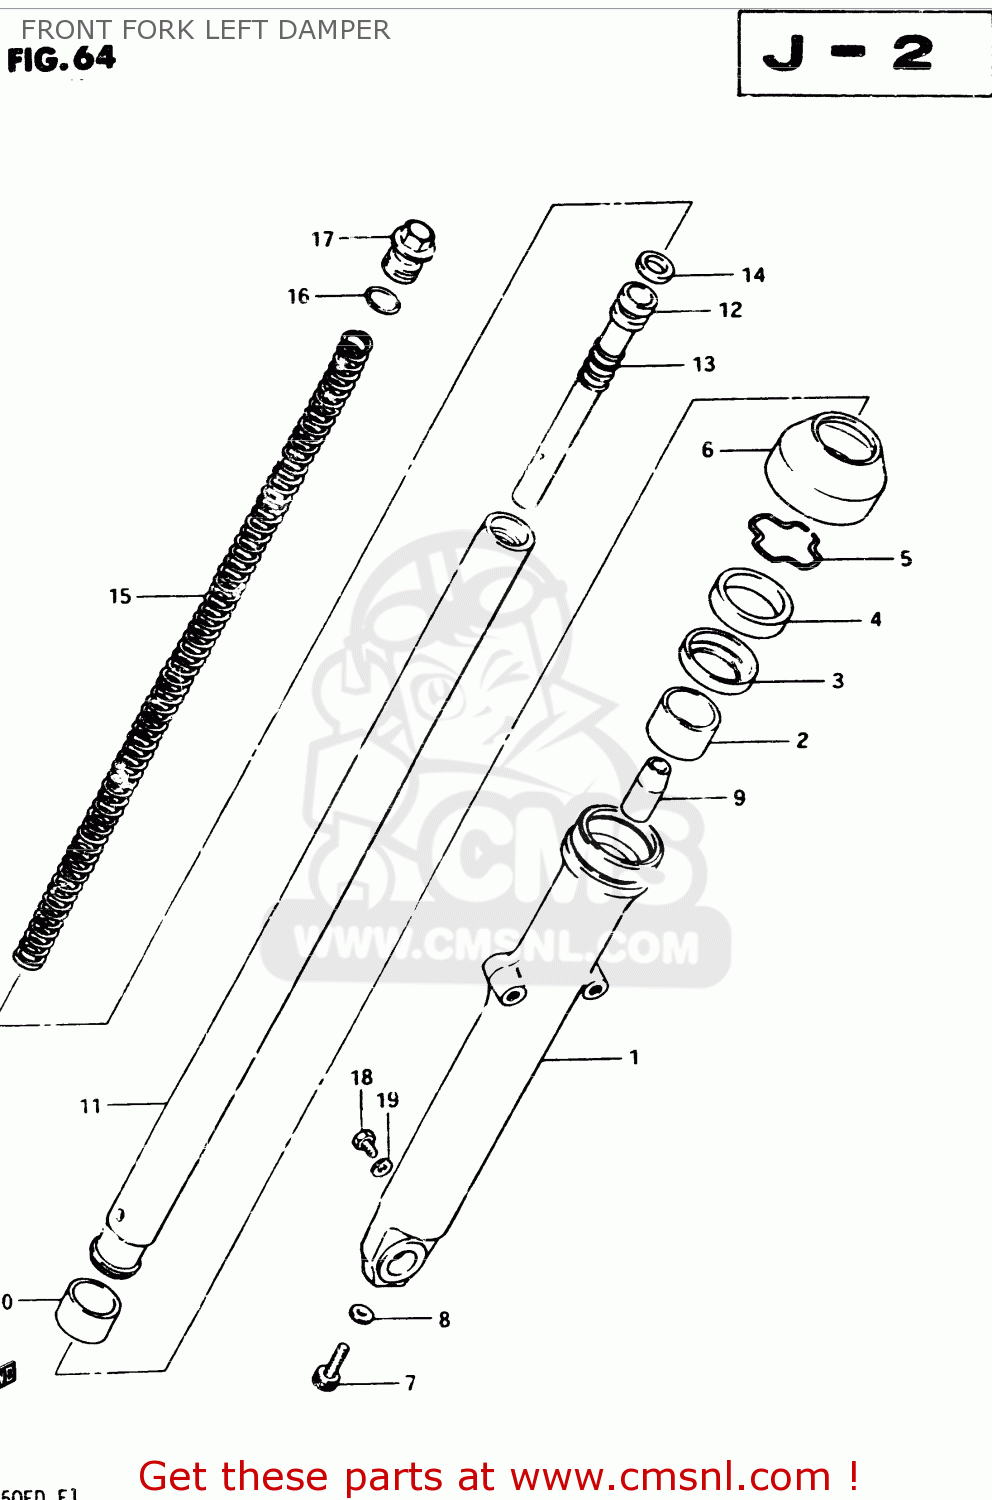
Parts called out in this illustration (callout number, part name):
1	OUTER TUBE RH
2	BUSH,GUIDE
3	SPACER,OIL SEAL
4	OIL SEAL,FRONT FORK
5	RING,BACKUP
6	DUST SEAL
7	DUST SEAL
8	BOLT(8X27)
9	GASKET (NAS)
10	BUSH
11	WASHER
12	LOCK WASHER
13	NUT
14	RING,PISTON
15	SPRING
16	O RING
17	BOLT
18	BOLT
19	CYLINDER, LH
20	SPRING,REBOUND
21	RING,PISTON
22	SPRING
23	O RING
24	BOLT
25	BOLT
26	GASKET,DRAIN,PLUG (NAS)
27	BOLT
28	BOLT
29	CAP
30	BREATHER
31	MODULATOR PARTS SET,FRONT
32	MODULATOR VALVE SET
33	O RING,FR FORK
